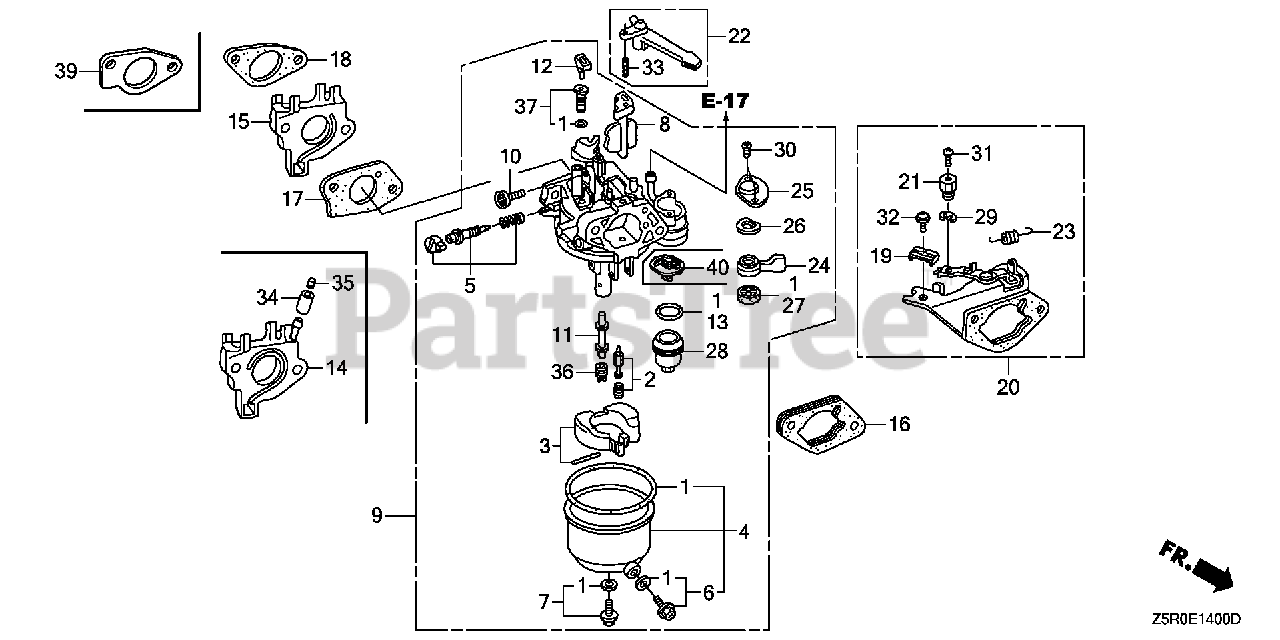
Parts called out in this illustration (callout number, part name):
1	GASKET SET (INCLUDE 16173-001-004) (INCLUDES 16173-001-004)
2	VALVE SET, FLOAT
3	FLOAT SET
4	CHAMBER SET, FLOAT
5	SCREW SET (Honda Code 4219879). (CARBURETOR NO.)
6	SCREW SET, DRAIN (Honda Code 1672187). (CARBURETOR NO.)
7	SCREW SET B
7	SCREW SET
8	CHOKE SET (CARBURETOR NO.)
9	CARBURETOR ASSY. (BE85B B)
10	SCREW, THROTTLE STOP
11	NOZZLE, MAIN (CARBURETOR NO.)
12	COLLAR, SET
13	GASKET, FUEL STRAINER CUP
15	INSULATOR, CARBURETOR
17	GASKET, CARBURETOR
18	GASKET, INSULATOR Use up to Engine SN 2949254.
19	HOLDER, CABLE
20	STAY ASSY., CHOKE CONTROL (REMOTE)
21	HOLDER, WIRE
23	SPRING, RETURN
24	LEVER, VALVE
25	PLATE, LEVER SETTING (CARBURETOR NO.)
26	SPRING, PETCOCK LEVER (CARBURETOR NO.)
27	GASKET, VALVE
28	CUP, FUEL STRAINER
29	CIRCLIP (5MM) Use from Engine SN 2327377.
30	SCREW, PAN (3X6)
31	SCREW, PAN (4X6)
32	SCREW-WASHER (5X16)
36	JET, MAIN (#88) Use up to Engine SN BE81B B.
36	JET, MAIN (#90) Use from Engine SN BE81B C.
36	JET, MAIN (#92)
37	JET SET, PILOT (#45)
